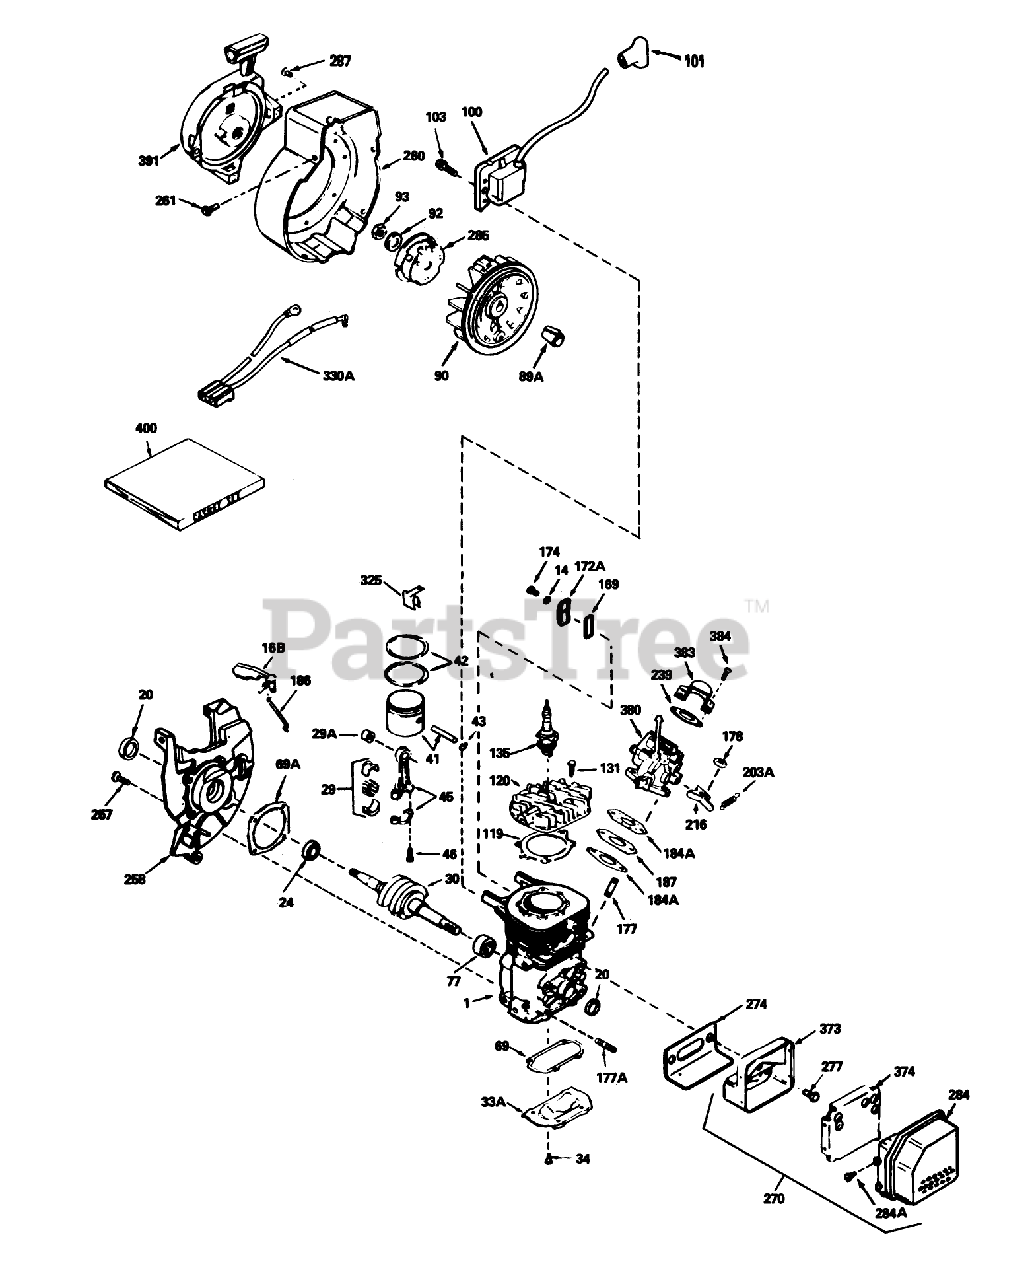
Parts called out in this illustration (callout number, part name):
1	Block Ass-y-Cylinder (Order Short Block if replacement is required.)
14	Washer
16B	Vane-Air
20	Seal-Oil
24	Bearing-Ball
29	Needle Bearing and Liner Set (37 Needles)
29A	Bearing-Cartridge
30	Crankshaft
33A	Plate-Cover
34	Screw (T-25, 10-24 x 1/2)
41	Piston (Incl. Ref. #43)
42	Ring Set
43	Ring-Retaning
45	Rod Assy.-Connecting (Incl. Ref. #3, 3A 3B)
46	Bolt-Rod, Connecting
69	Gasket-Plate, Cover
69A	Gasket-Cover, Cylinder
77	Bearing-Cartridge
89A	Blade (20 inch)
90	Flywheel
92	Washer-Belleville
93	Nut-Flywheel
100	Solid State
101	Cover-Spark Plug
103	Screw
119	Gasket-Head, Cylinder
120	Head-Cylinder
131	Screw (T-30, 1/4-20 x 3/4)
135	Spark Plug-Resistor (R C J 8Y)
169	Cover-Compression, Release
172A	Comp. Release Cover
174	Screw (T-25, 10-24 x 1/2)
177	Stud-Carburetor
178	Nut and Lock Washer (1/4-28)
184A	Gasket-Carburetor
186	Link-Governor
187	Spacer
203A	Spring-Governor
216	Lever-Adjusting, Rpm
239	2060A77 WIZARD ROTA
257	Screw (T-30, 1/4-20 x 5/8)
258	Base Assy.-Blower Housing (Incl. Ref. #10)
260	Housing-Blower
261	Screw (1/4-20 x 1/2)
270	Muffler Assembly (Incl. Ref. #53-57)
274	Gasket-Exhaust
277	Screw (T-30, 1/4-20 x 5/8)
284	Cover Muffler
284A	Screw
285	Cup-Starter
287	Rivet-Pop
325	Clip-Wire
330A	Harness-Wire
373	Base-Muffler
374	Baffle-Muffler
380	Carburetor (Incl. Ref. #184A)
383	Baffle-Carburetor
384	Screw
391	Starter-Rewind
400	Gasket Set
